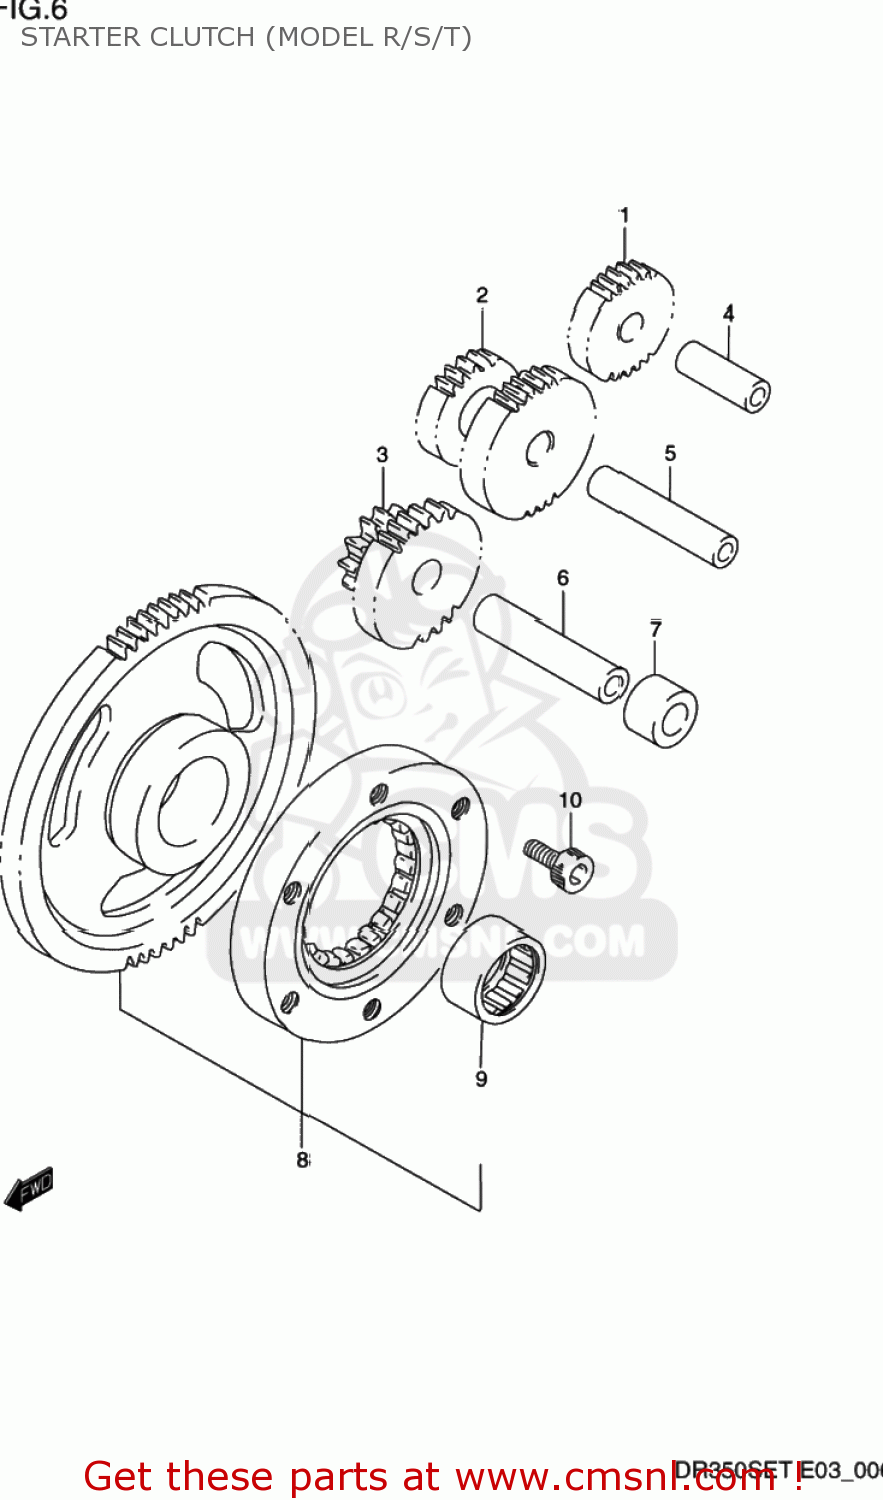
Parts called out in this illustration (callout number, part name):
1	GEAR,STARTER IDLE NO.1(NT:34)
2	GEAR,STRTR IDLE NO.2(NT:22/47)
3	GEAR,STARTER IDLE NO.3
4	PIN(6X10X32)
5	PIN(6X10X55.5)
6	PIN(12X55.5)
7	SPACER (12.2X20X13)
8	CLUTCH SET,STARTER
9	BEARING(29X36X18)
10	BOLT
